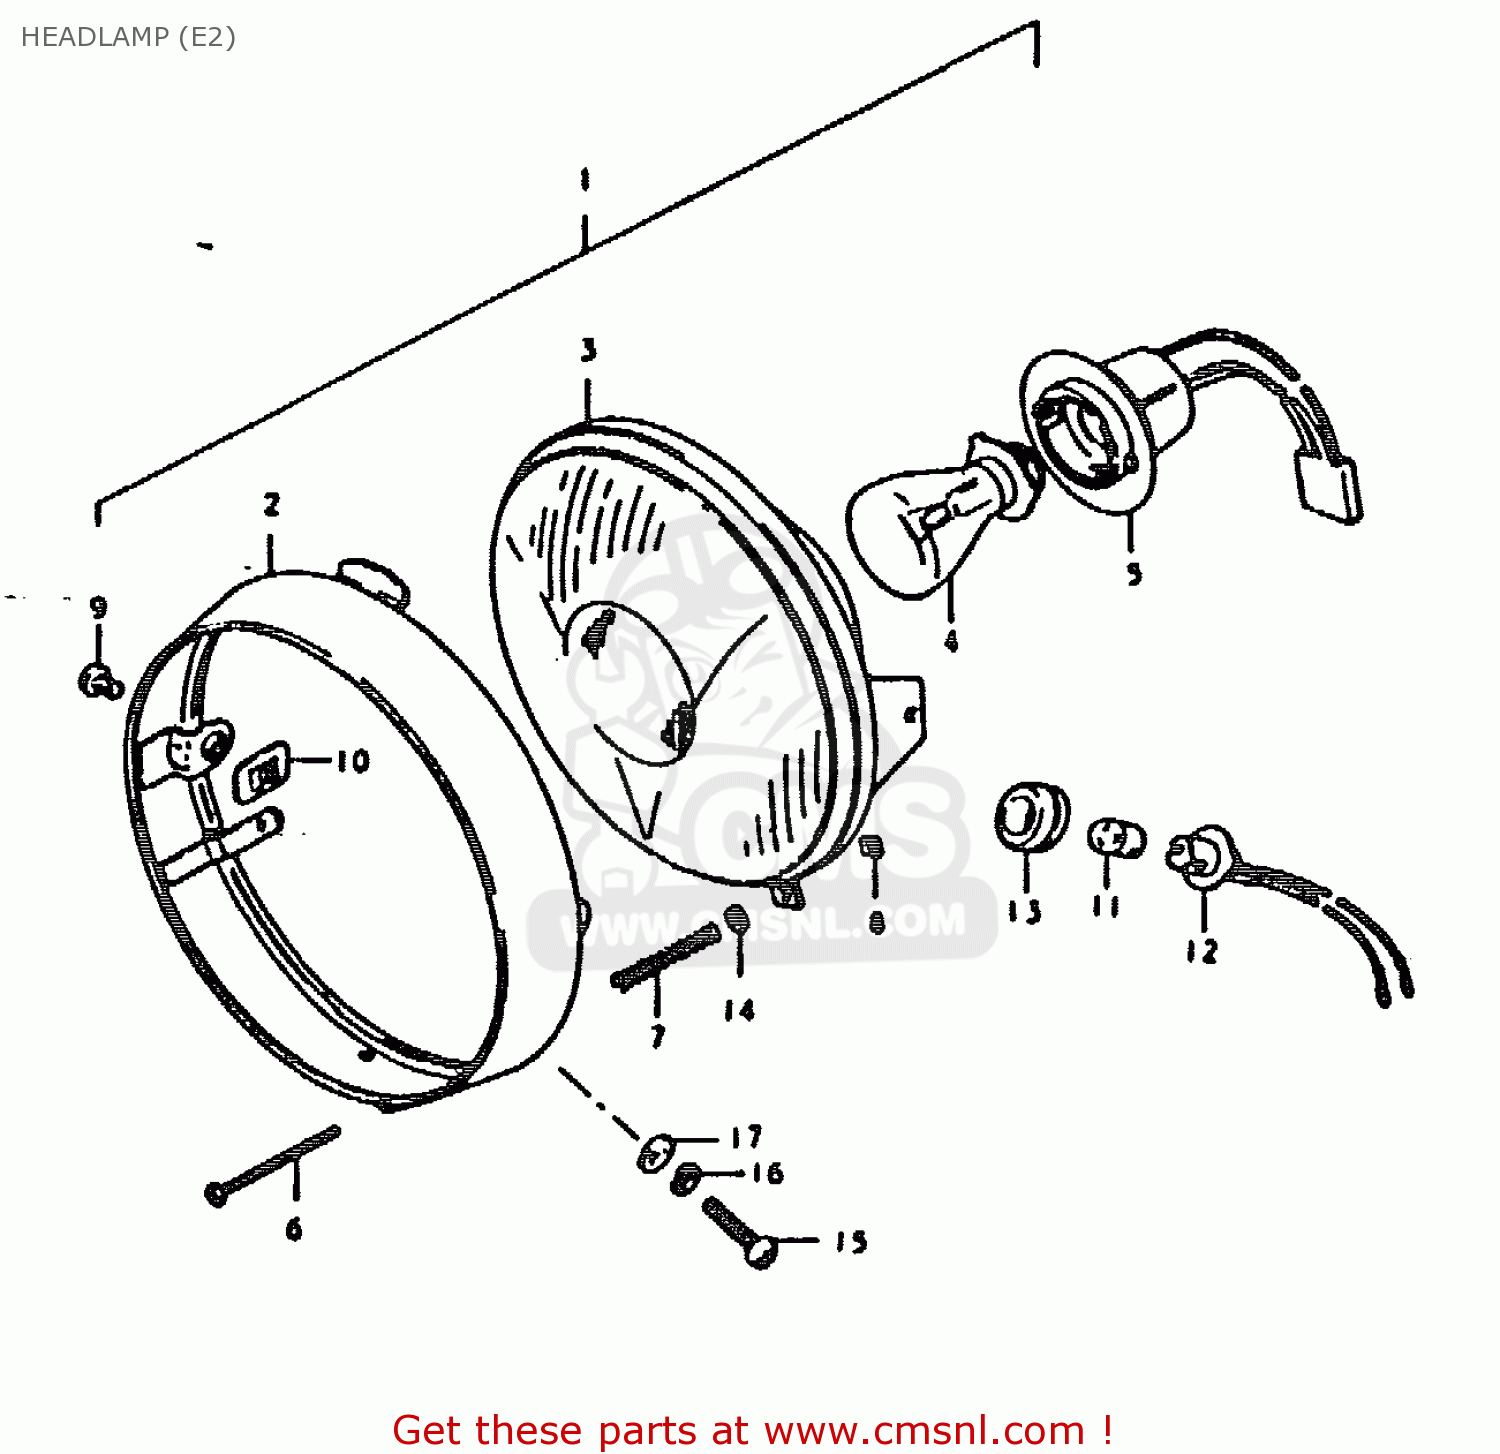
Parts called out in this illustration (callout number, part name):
1	HEADLAMP ASSY
2	RIM
3	UNIT
4	BULB(6V25/25W,STANLEY,A7007)
5	SOCKET,HEADLAMP
6	SCREW,HEADLAMP ADJUST
7	SPRING
8	NUT,HEADLAMP ADJUSTER
9	SCREW
10	NUT
11	BULB(6V/3W)
12	SOCKET
13	SEAL,PARKING BULB
14	WASHER
15	SCREW
16	LOCK WASHER
17	WASHER
